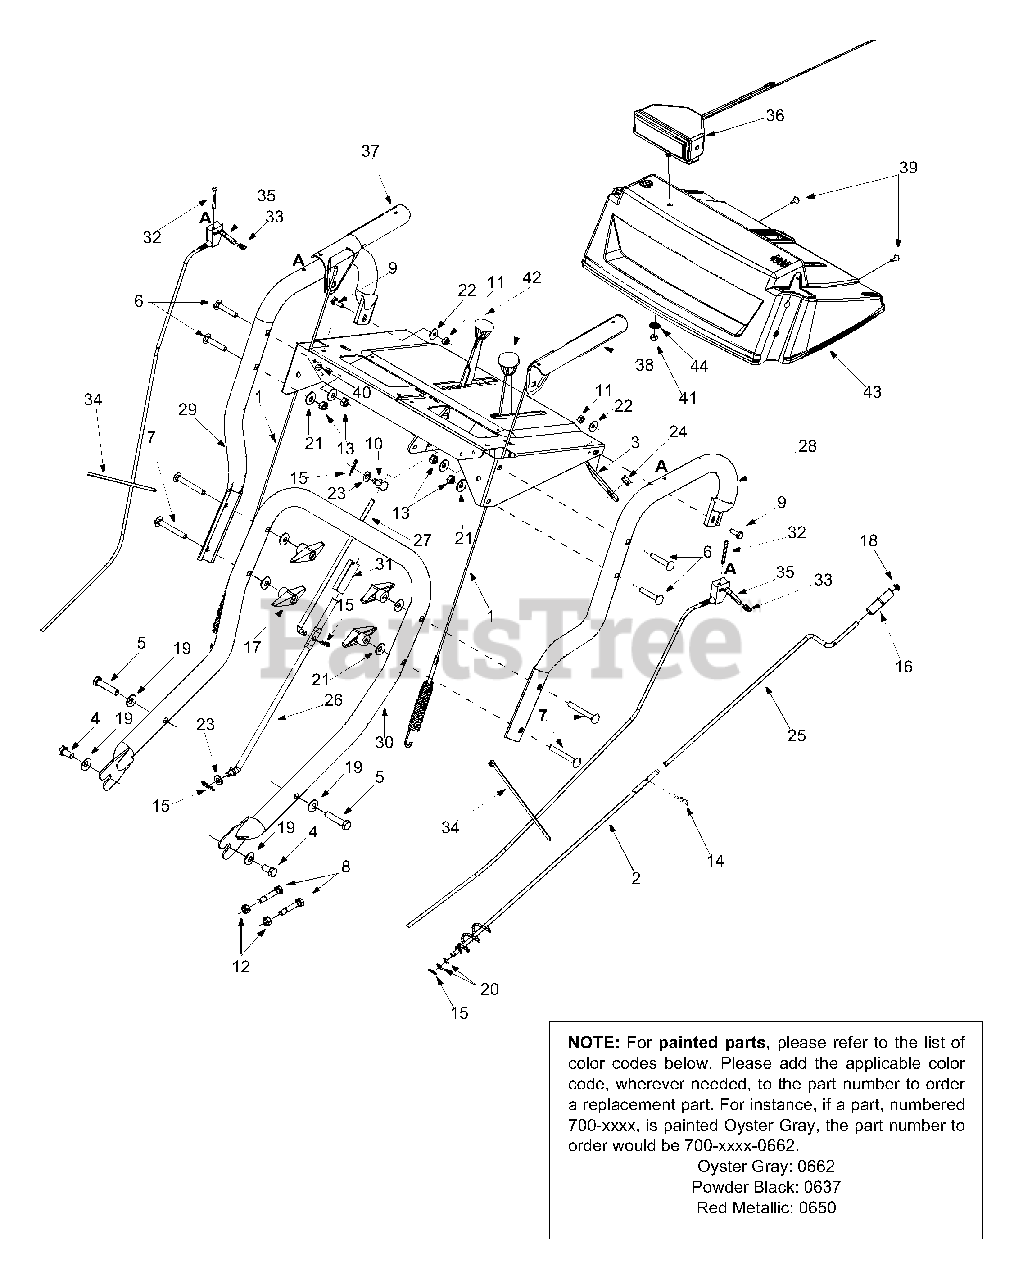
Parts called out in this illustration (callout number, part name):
1	Cable Assembly: Auger/Drive
2	Chute Crank Assembly
3	Chute Crank Bracket
4	Hex Screw 3/8-16 x .75"
5	Hex Screw 3/8-16 x 1.75"
6	Carriage Bolt 5/16-18 x 1.75"
7	Carriage Bolt 5/16-18 x 2.5"
8	Shear Bolt 5/16-18 x 1.75"
9	Hex Screw 1/4-20 x .75"
10	Ferrule
11	Hex Nut 1/4-20
12	Hex Lock Nut
13	Hex Nut
14	Hairpin Clip
15	Hairpin Clip
16	Chute Crank Knob
17	Knob
18	Push Cap
19	Bell Washer
20	Flat Washer
21	Beleville Washer
22	Bell Washer
23	Flat Washer
24	Plastic Bushing
25	Chute Crank
26	Lower Shift Rod
27	Upper Shift Rod
31	Clutch Rod Connector
32	Oval C-Sunk Screw
33	Flat Weld Nut
34	Cable Tie
35	Trigger Control
36	Light Assembly
36	Halogen Lamp
36	Lens Assembly
37	Handle Engagement RH
38	Handle Engagement LH
39	Special B Screw
40	Hex Sems Nut
41	Hex Lock Nut
42	Shift Knob
43	Handle Panel
44	5/16 Washer
